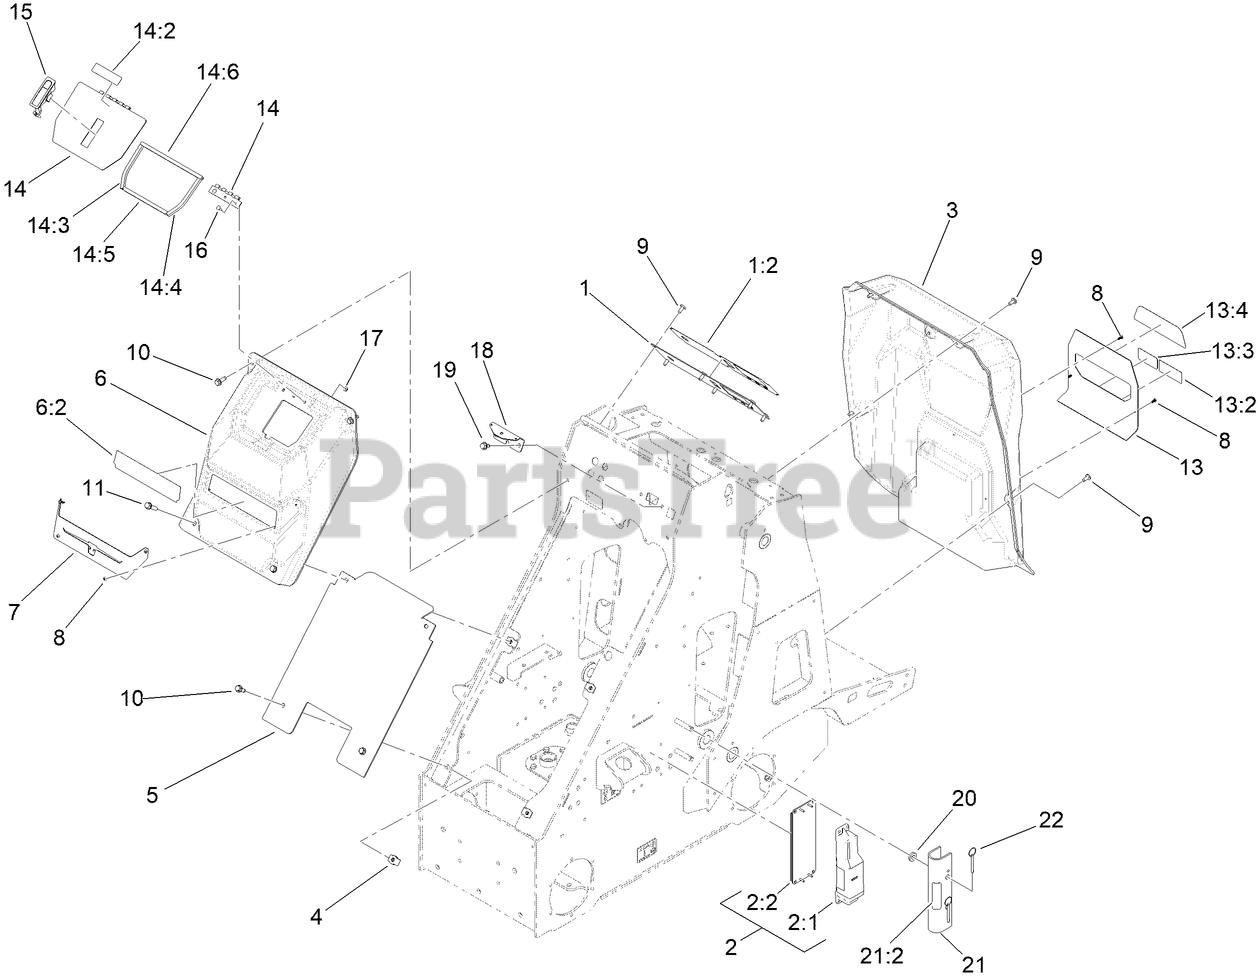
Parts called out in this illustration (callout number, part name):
1	PANEL-INSTRUMENT [SUNBELT]
1:2	DECAL - CONTROLS
2	M4 KIT ASM
2:1	M4, ZTR
2:2	M4 MOUNTING BRACKET KIT
3	PANEL-SERVICE
4	NUT-TINNERMAN
5	COVER-FRONT,LOWER
6	HOOD ASM, FRONT
6:2	DECAL - BACKER, RED
7	PLATE-HOOD
8	SCREW-PLASTITE, TORX PAN
10	SCREW-HWH
11	SCREW-HWH
13	PLATE - CORD [SUNBELT]
13:2	DECAL - CHARGING PORT
13:3	DECAL-BATTERY CHARGER
13:4	DECAL-HYPERCELL
14	DOOR - ACCESS
14:2	DECAL-SERVICE, SHUT-OFF
14:3	FOAM - DOOR, RH
14:4	FOAM - DOOR, LH
14:5	FOAM - DOOR, BOTTOM
14:6	FOAM - DOOR, TOP
15	LATCH - COMPRESSION
16	BOLT-CARR
17	NUT-HF
18	BRACKET - LIGHT
19	SCREW-HWH
20	WASHER-NEOPRENE
21	LOCK CYLINDER ASM [SUNBELT]
21:2	DECAL - CYLINDER LOCK
22	PIN-COTTERLESS
